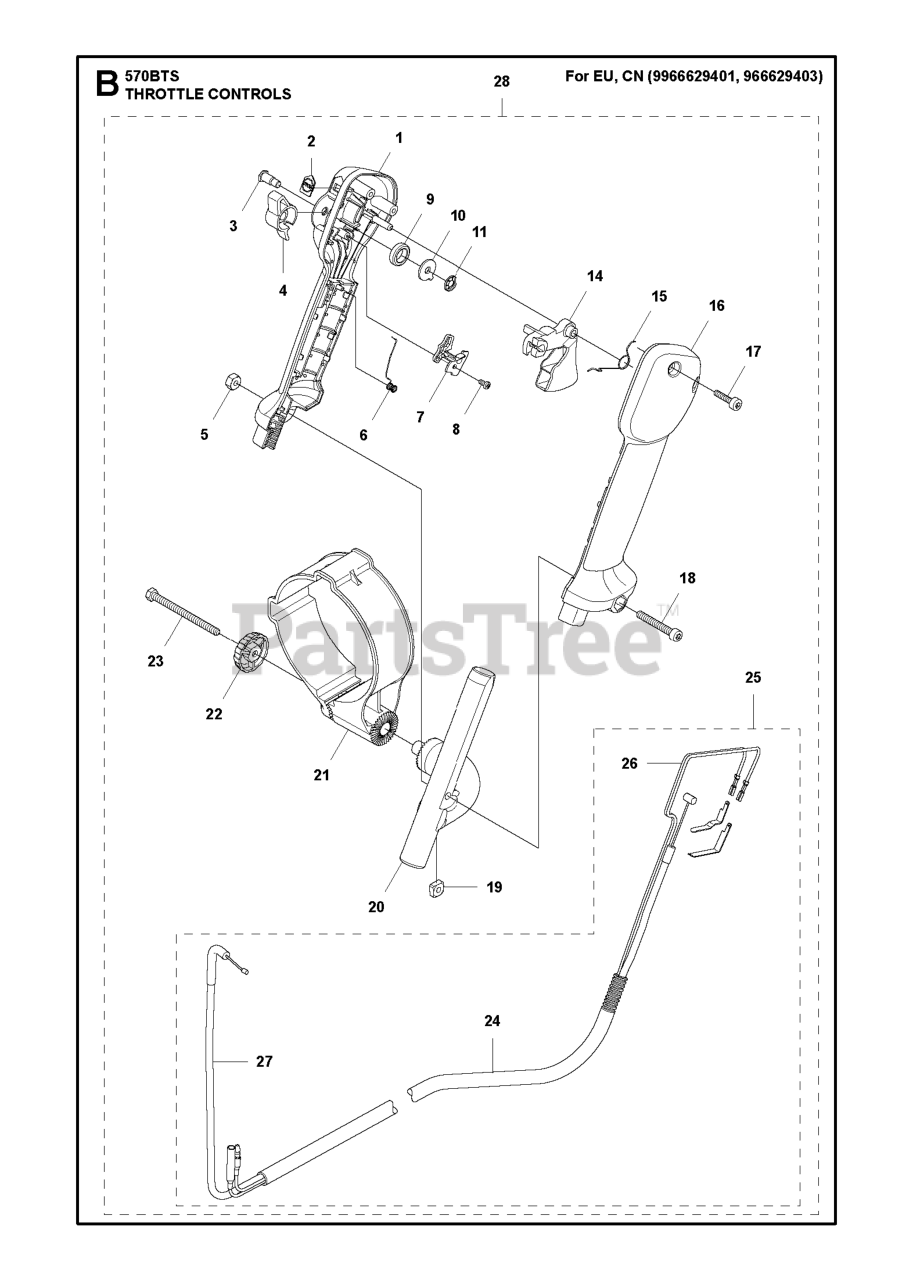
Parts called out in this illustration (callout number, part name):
1	HANDLE HALF (L)
3	SHAFT PIVOT
4	LEVER STOP
14	TRIGGER 848L5W34C0
16	HANDLE HALF (R)
17	SCREW
19	SQUARE NUT M5
20	HOLDER, HANDLE
21	HANDLE HOLDER
22	KNOB
25	WIRING ASSY
26	CORD COMPLETE
27	CABLE, COMP
28	ASSY LEVER SET
